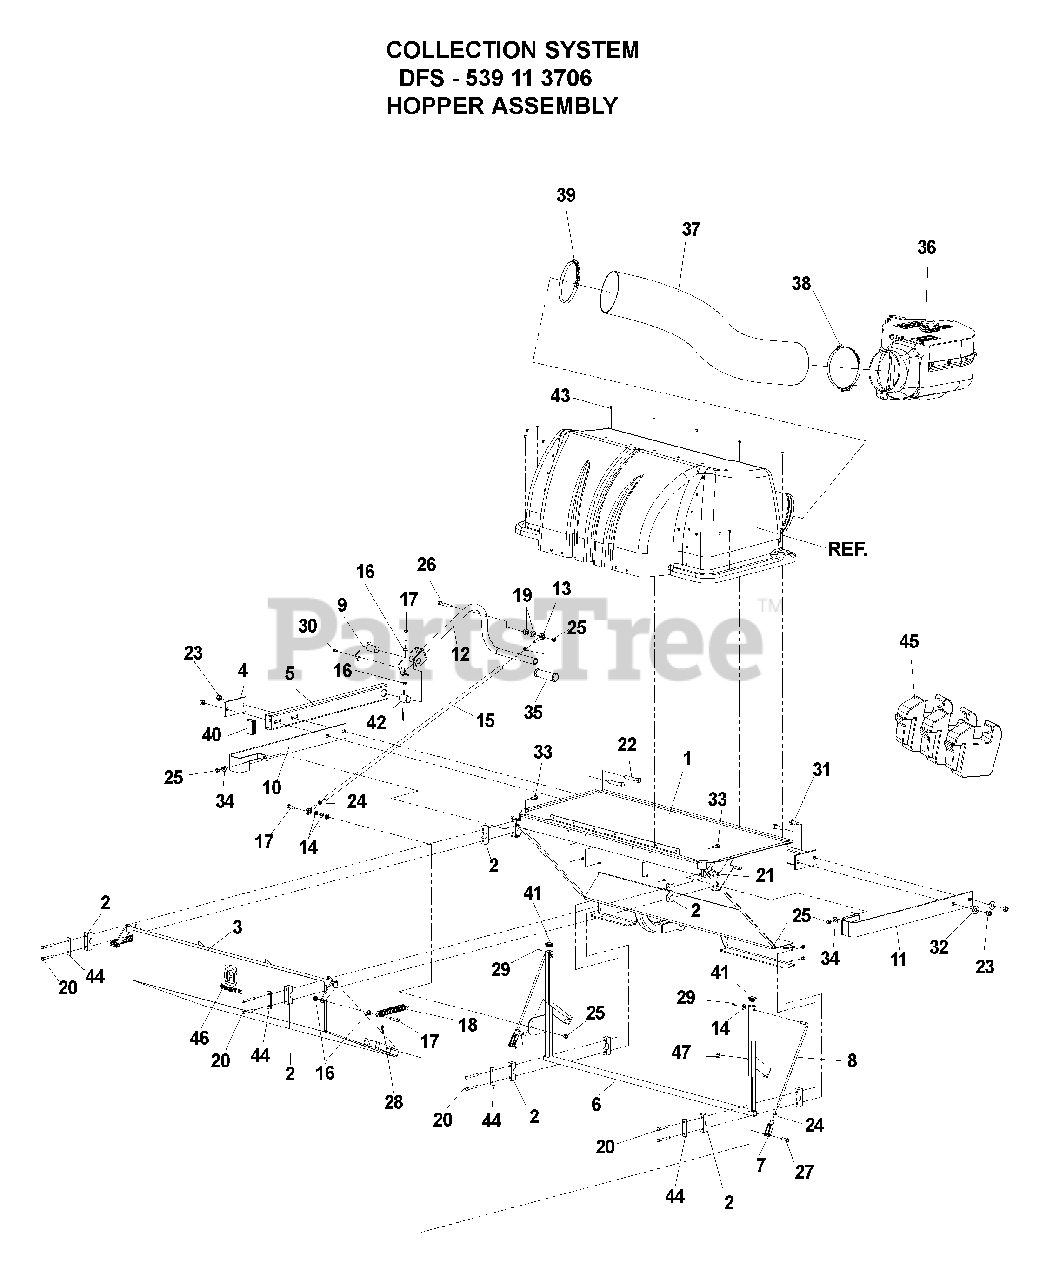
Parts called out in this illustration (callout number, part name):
2	PILLOW BLOCK
4	PLATE - BACKING
5	TUBE, SUPPORT, HANDLE
6	BELL CRANK
7	YOKE, 3/8F
9	PIN, PIVOT
10	GUARD, LEFT
11	GUARD, RIGHT
13	ROD END, 3/8-24, RH
14	WASHER, 3/8, SAE
15	TUBE, THREADED
16	NUT, 3/8-16, WHIZLK
17	HCS, 3/8-16 X 1 1/2, GR5
20	HCS, 5/16-18 X 2 1/2, GR5
21	NUT, 5/16-18, NYLOC
22	HCS, 1/2-13 X 3, GR5
23	NUT, 1/2-13, NYLOC
24	NUT, 3/8-24, JAM
25	NUT, 3/8-16, NYLOC
26	HCS, 3/8-16 X 2 3/4, GR5
27	PIN CLEVIS, 3/8 X 1 1/4
28	HAIRPIN COTTER
29	PIN, COTTER, 1/8 X 3/4
30	SCREW, 1/4C X 3/8, THREAD FORMING
31	HCS, 1/2-13 X 1 1/4, GR5
32	WASHER, 1/2
33	HCS, 3/8-16 X 1, GR5
34	WASHER, 3/8
35	GRIP, HANDLE
36	BLOWER
38	OVER CENTER BAND
39	HOSE CLAMP, 6-7
40	PLUG, RECTANGULAR TUBING
41	PLUG, SQUARE TUBE
42	BUSHING, 1
43	RIVET, 3/6, STAVEX
44	REINFORCEMENT BAR
45	WEIGHT CAST, FRONT
46	DECAL, CROWN
47	GROMMET, BUMPER 69
539113706	Hopper Assembly Collection (DFS)
